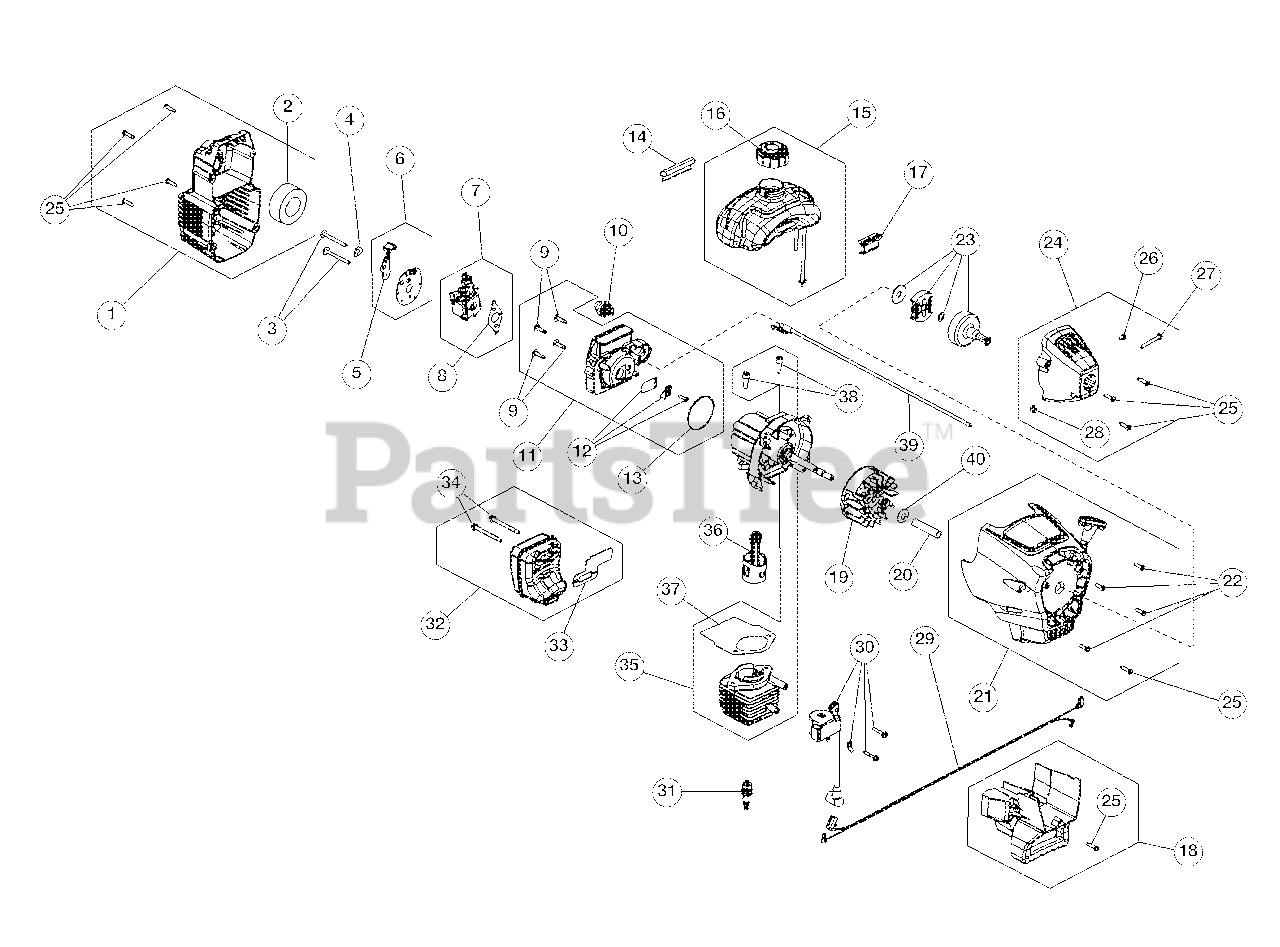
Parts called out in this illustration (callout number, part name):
1	Air Cleaner Cover Assembly (Incl. 2 & 25)
2	Air Cleaner Filter
3	Carburetor Mounting Screw Assembly
4	Wavey Washer
5	Choke Lever Assembly
6	Choke Plate Assembly (Incl. 5)
7	Carburetor Assembly (Incl. 8)
8	Carburetor Gasket
9	Carb Mount Screw
10	Primer & Hose Assembly
11	Carb Mount Assembly (Incl. 9, 12 & 13)
12	Reed Assembly
13	O-Ring
14	Rear Mounting Pad
15	Fuel Tank Assembly (Incl. 16)
16	Fuel Cap Assembly
17	Front Mounting Pad
18	Shroud Extension & Stand (Incl. 25)
19	Flywheel Assembly
21	Starter Housing Assembly (Incl. 22 & 25)
22	Housing Screw
23	Clutch Rotor Assembly
24	Clutch Cover Assembly (Incl. 25-28)
25	Cover Screw
26	Anti-Rotation Screw
27	Clamping Screw
28	Clamping Nut
29	Wire Leads and Sleeve
30	Module Assembly
31	Spark Plug
32	Muffler Assembly
33	Exhaust Gasket
34	Muffler Mounting Bolts
35	Cylinder Assembly (Incl. 37 & 38)
36	Piston and Rod Assembly
37	Cylinder Gasket
38	Cylinder Bolt
39	Throttle Cable
40	Washer
